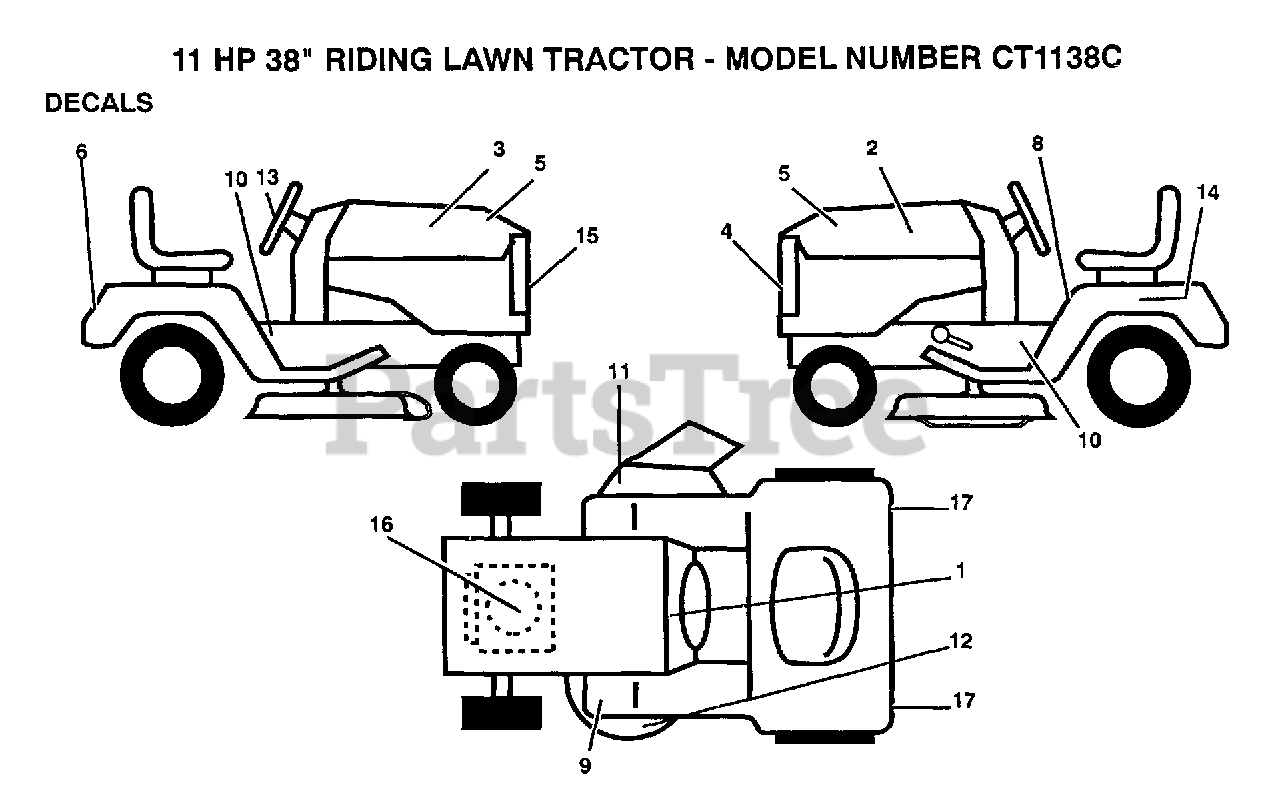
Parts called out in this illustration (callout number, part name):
4	GRILL DECAL
5	DECAL HP HOOD
6	FENDER DECAL
8	DECAL CAUTION
9	DECAL T
11	DECAL WARNING
12	DECAL YT
13	"DECAL,STR WHL"
14	DECAL
16	DECAL.ENG.27164
17	REFLECTOR-TAIL YT
